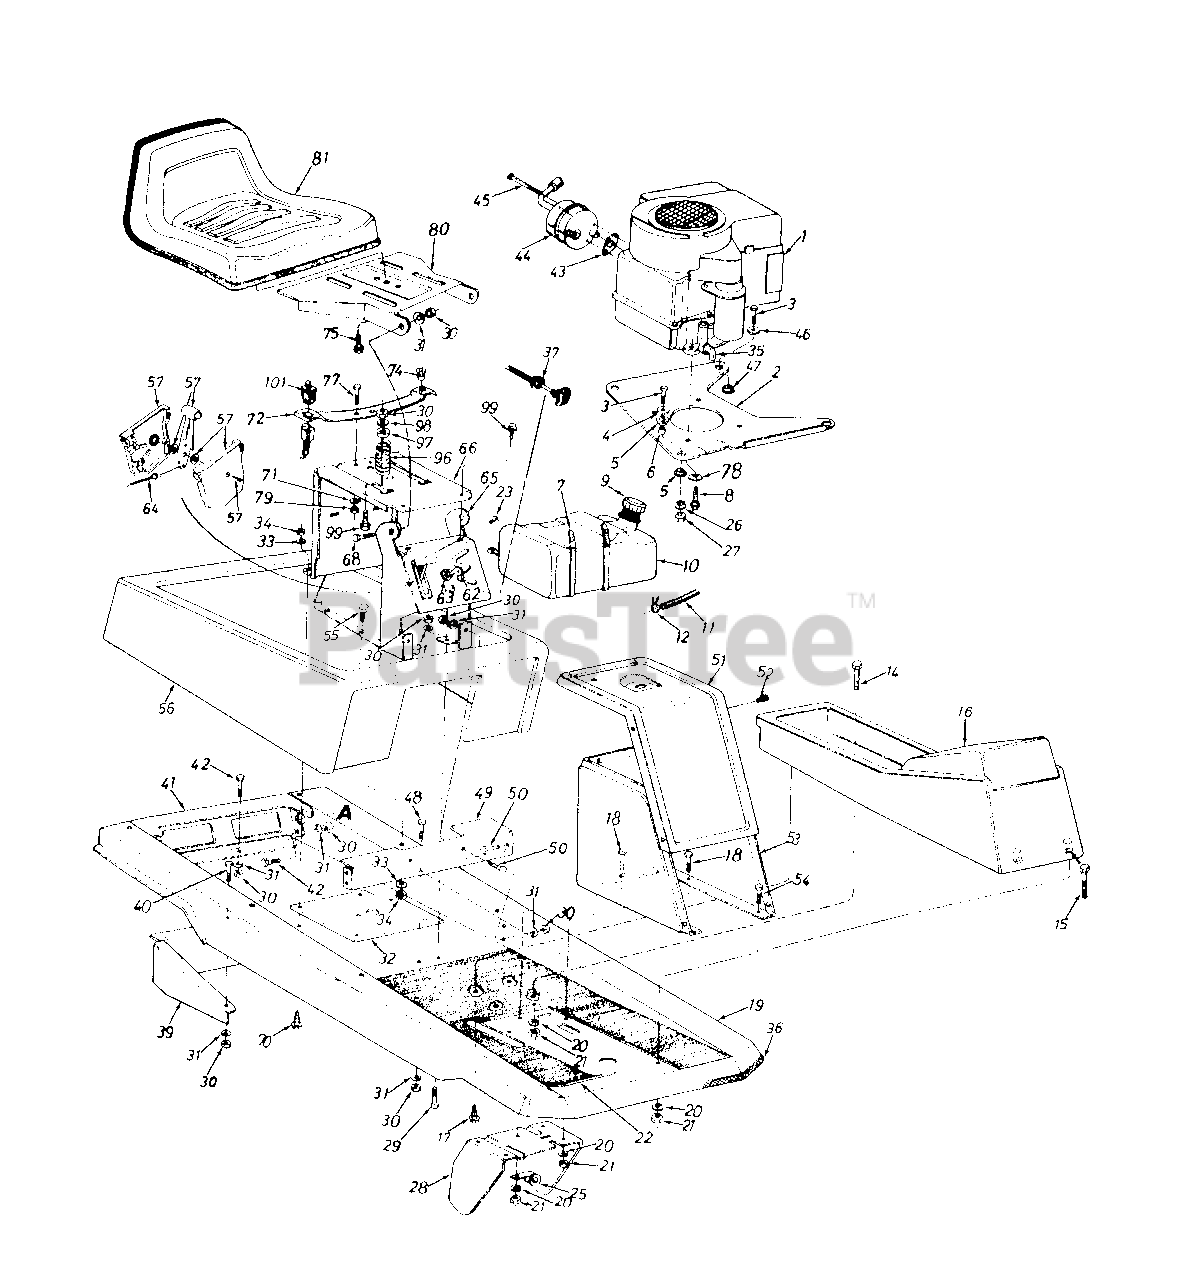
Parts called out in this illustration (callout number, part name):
1	Engine
4	Fl-Wash. .330" I.D. x 1.125" O.D.
5	Engine Mounting Grommet
6	Spacer .315" I.D. x .50" O.D. x .520" Lg.
7	Cable Tie 30.6 Lg.
8	Hex Wash. Hd. Self-Tap Scr. 3/8-16 x 1.25" Lg.
9	Gas Cap
10	Fuel Tank
11	Fuel Line - 26" Lg.
12	Hose Clamp - 1/2" O.D. Tube
14	Hex Bolt 5/16-18 x 1.75" Lg.
15	Hex Bolt 5/16-18 x 2" Lg.
16	Front Console
17	Plastite Scr. 5/16 x 1.25" Lg.
18	Hex Bolt 5/16-18 x .75" Lg.
19	Main Frame
20	L-Wash. 5/16" I.D.
21	Hex Nut 5/16-18 Thd.
22	Floor Mat
23	Truss Mach. AB-Tap Scr.#10 x .50" Lg.
25	Clamp
26	L-Wash. 5/16" I.D.
27	Hex Nut 5/16-24 Thd.
28	Clutch-Brake Pedal Ass'y.
29	Hex Bolt 5/16-18 x .75" Lg
30	Hex Nut 5/16-18 Thd.
31	L-Wash. 5/16" I.D.
34	Hex Nut 1/4-20 Thd.
35	90° Elbow Male To Female
36	Trim Strip
37	Choke Control
43	Exhaust Gasket (8 H.P. B&S)
44	Muffler Ass'y. (8 H.P. B&S)
45	Shld. Bolt (8 H.P. B&S)
46	Fl-Wash. .330" I.D. x 1.25" O.D.
47	Flange Wash. .320" I.D. x .750" O.D.
49	Seat Support & Frame Brkt.
50	Hex Bolt 5/16-18 x .75" Lg.
55	Hex Bolt 1/4-20 x .50" Lg.
62	Ignition Key
63	Ignition Switch
64	Throttle Control Wire 35" Lg.
65	Front Seat Bracket
70	Hex Tap Scr. 1/4-20 x 1.0" Lg.
71	L-Wash. 5/16" I.D.
72	Seat Spring
74	Grommet
75	Hex Bolt 3/8-16 x .62" Lg. (Gr. 5)
77	Hex Bolt 5/16-18 x .75" Lg.
78	Bell-Wash. .345" I.D. x .88" O.D.
79	Hex Cent. L-Nut 5/16-18 Thd.
81	Seat Ass'y. Comp.
96	Compression Spring 2.7" Lg.
97	Bushing
98	Fl-Wash. .344" I.D. x .875"
99	Hex Bolt 5/16-18 x 1" Lg. (Gr. 5)
101	Seat Switch
